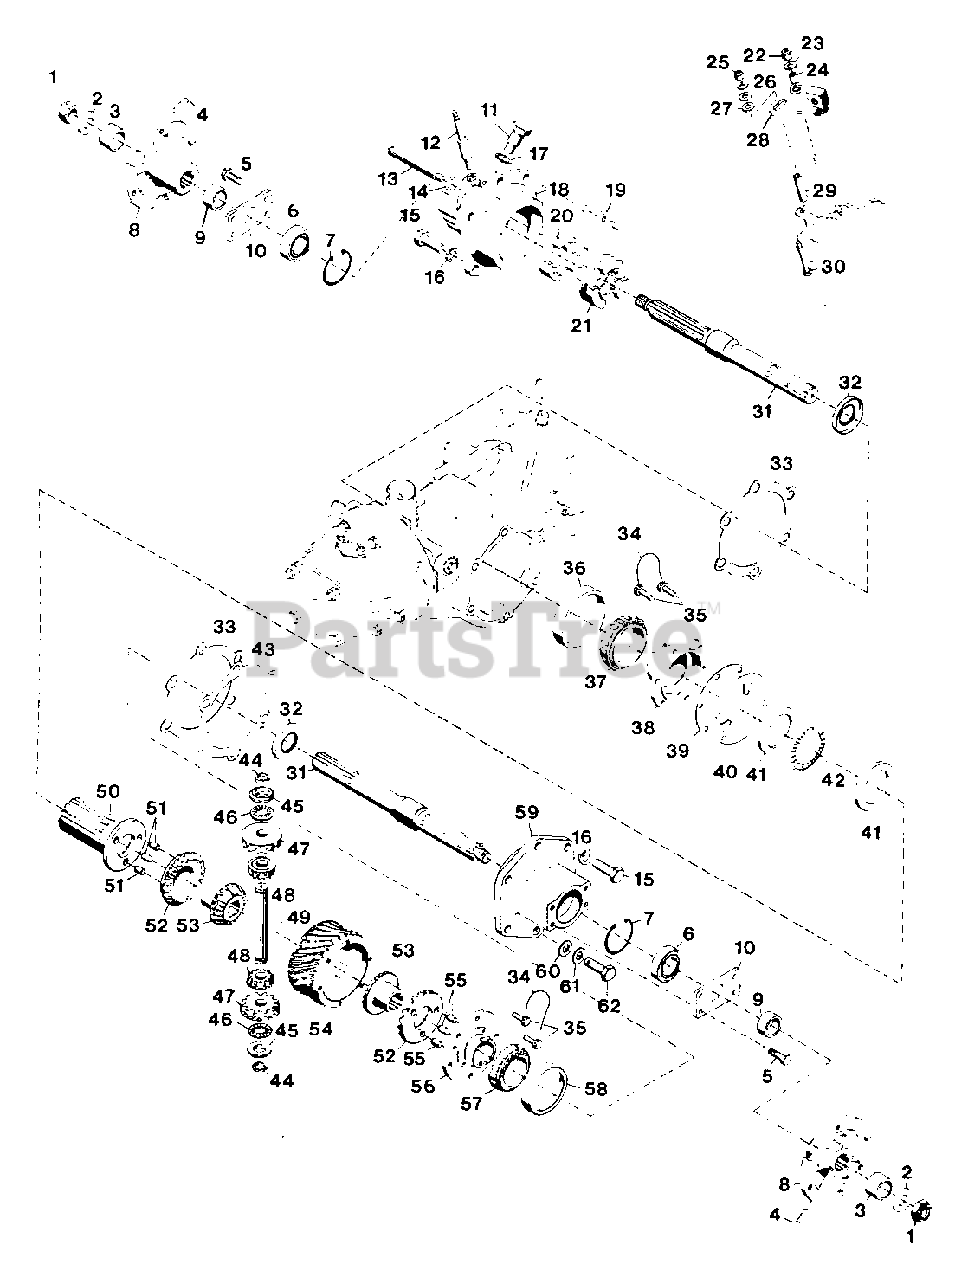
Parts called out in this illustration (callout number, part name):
1	Nut, Hex 3/4-10 Light Thin
2	Washer, Flat .812x1.469x.134
3	Spacer
4	Screw, Set 7/16-14x1.0 SCP
5	Bolt, Hex 3/8-16x.750
6	Bearing, Ball 1.000x2.000x.562
7	Ring, Retaining 2.000 Bore
8	Hub, Wheel
9	Spacer
10	Plate, End
11	Bolt, Stationary Clutch
12	Pivot, Stationary
13	Pin, Clutch Sliding
14	O-Ring, .438x.625x.094
15	Bolt, Hex 1/2-13x1.00
16	Washer, Lock 1/2 Reg.
17	Washer, Oil Strainer Nut
18	Housing, Axle 2-Speed
19	Yoke, Shifting
20	Clutch, Stationary
21	Clutch, Shifting
22	Nut, Lock 5/16-18
23	Washer, Flat .344x.688x.065
24	Bushing, Nylon .375x.503x.875
25	Nut, Lock 1/4-20
26	Washer, Flat .281x.625x.065
27	Washer, Flat .406x.812x.065
28	Weldment, Arm Shifter
29	Bushing
30	Bolt, 1/4-20x2.25 Gr. 8 PHD
31	Axle, Straight
32	Seal, Oil 1.188x2.000x.250
33	Gasket, Axle Housing
35	Bolt, Special 5/16-18
36	Cup, Roller Bearing
37	Cone, Roller Bearing
38	Housing, Clutch
39	Shim, Worm Gear .020
40	Shim, Worm Gear .005
41	Race, Thrust 2.00x2.740x.031
42	Bearing, Needle Thrust .060
43	Shim, Axle Housing .005
44	Ring, Retaining .750 Shaft
45	Spacer, .765x1.245x.200
46	Brg, Needle Thst.752x1.240x.078
47	Gear, Diff. Shifting Bevel
48	Gear, Spider Bevel
49	Pin, Spider
50	Shifter, Splined Pinned
51	Pin, Dowel .375x.375
52	Gear, Pinned Bevel
53	Gear, Differential Bevel
54	Gear, Worm 8 Start
55	Pin, Dowel .375x.500
56	Housing, Pinned
57	Cone, Roller Bearing
58	Cup, Roller Bearing
59	Housing, Axle
60	Seal, Oil Drain
61	Washer, Flat .531x1.062x.095
62	Bolt, Hex 1/2-13x1.00 Nylon Ins.
